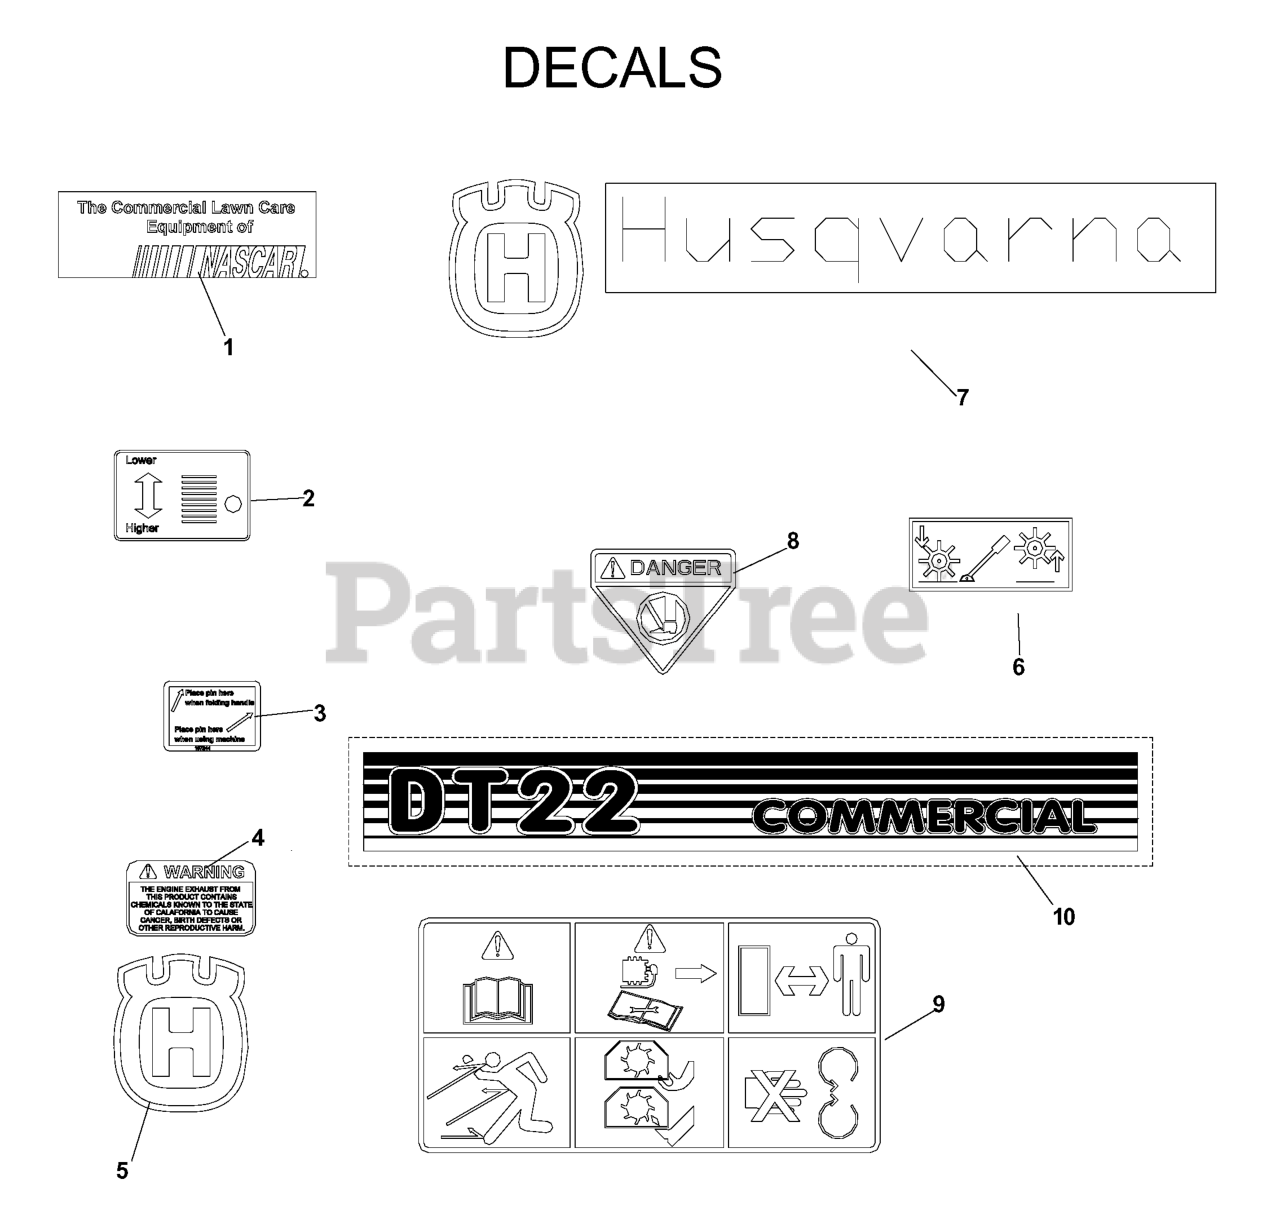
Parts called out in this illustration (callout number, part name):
1	DECAL, NASCAR
2	DECAL, PEDAL HEIGHT
3	DECAL, HANDLE PIN
4	DECAL, PROP. 65
5	DECAL, CROWN H
6	DECAL, HEIGHT ADJUST
7	DECAL - 12" HUSQVARNA W/CROWN
8	DECAL, FOOT DANGER
9	DECAL, SAFETY GRAPHICS
10	DECAL, DT22B
